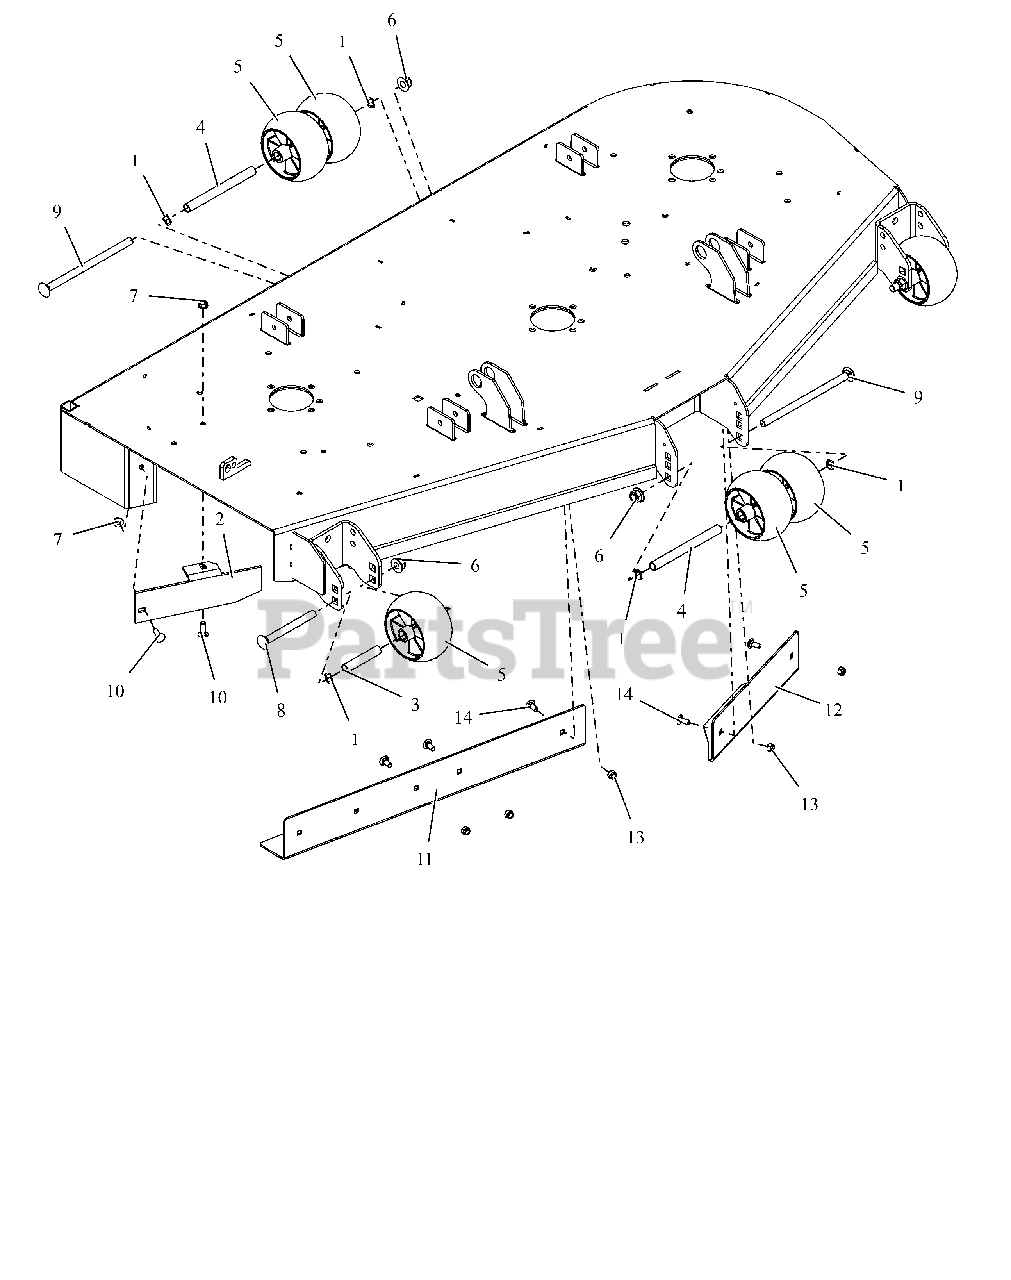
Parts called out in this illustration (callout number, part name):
1	WAVE WASHER .531X.781X.125FH
2	60" DISCHARGE BAFFLE - RED
3	SPACER, .510X.625X3.35
4	SPACER, .510X.625X6.50
5	ANTI-SCALP WHEEL - 5X3 CTR
6	NUT,NYL-FLG .50-13 GF ZCC
7	NUT,NYL-FLG .31-18 GF ZCC
8	BLT, RHSN .50-13X5.00 G5 ZCC
9	BLT, RHSN .50-13X8.50 G5 ZCC
10	BLT,RHSN .31-18X1.00 G5 ZCC
11	BAFFLE, 60" RH VACUUM (RED)
12	BAFFLE, 60" LH VACUUM (RED)
13	NUT,NYL .31-18 G5 ZCC
14	BLT,RHSN .31-18X.75 G5 ZCC
